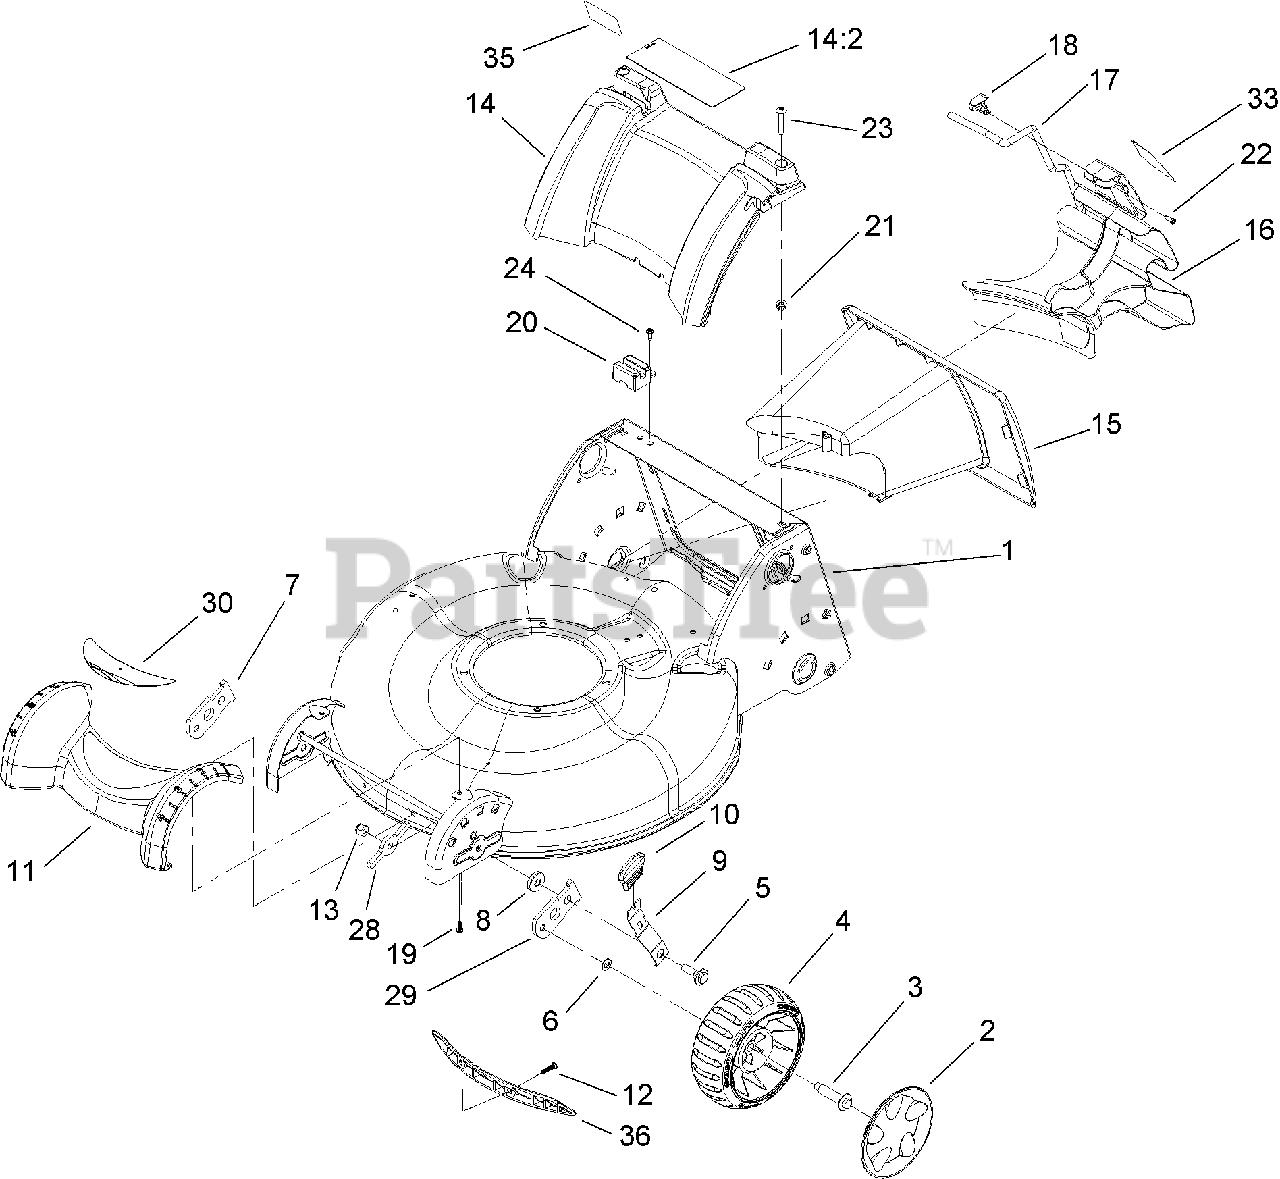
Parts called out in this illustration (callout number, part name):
1	HOUSING ASM
2	COVER-WHEEL, 7 INCH
3	BOLT-SHOULDER
4	7 INCH WHEEL ASM
5	BOLT-SHOULDER
7	ARM-PIVOT, RH
9	ARM-SPRING
10	KNOB-LEVER, HOC
11	COVER-FRONT
12	SCREW-PLASTITE
13	NUT-LOCK, NI
14	COVER-REAR
14:2	DECAL-SAFETY
15	TUNNEL
16	PLUG-CHUTE
17	LATCH-PLUG
18	RETAINER-LATCH
19	SCREW-PLASTITE
20	MODULE-SWITCH
21	NUT-CLIP
22	SCREW-PPH
23	SCREW-PTH
24	SCREW-THREAD FORMING
28	WASHER-SUPPORT, FRONT
29	ARM-PIVOT, LH
35	DECAL-BAG ATTACHMENT
36	INSERT-HOUSING
